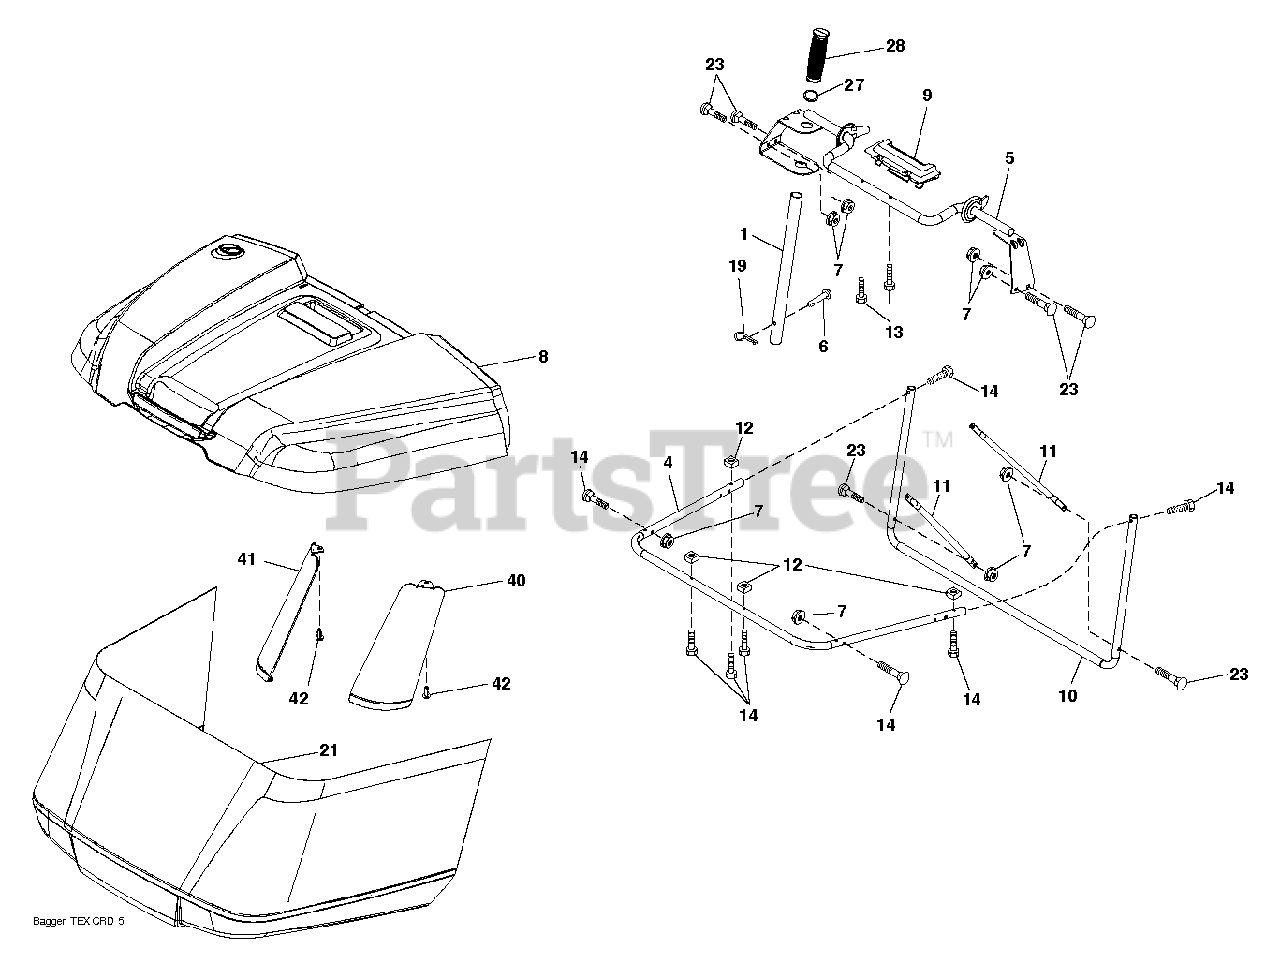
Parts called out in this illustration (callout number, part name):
1	TUBE.PNT.HDL.BAGGER.
6	RIVET,DRILLED
7	NUT T
19	PIN.COTTER.5/16.BOW TI
28	GRIP.HANDLE.BLACK
